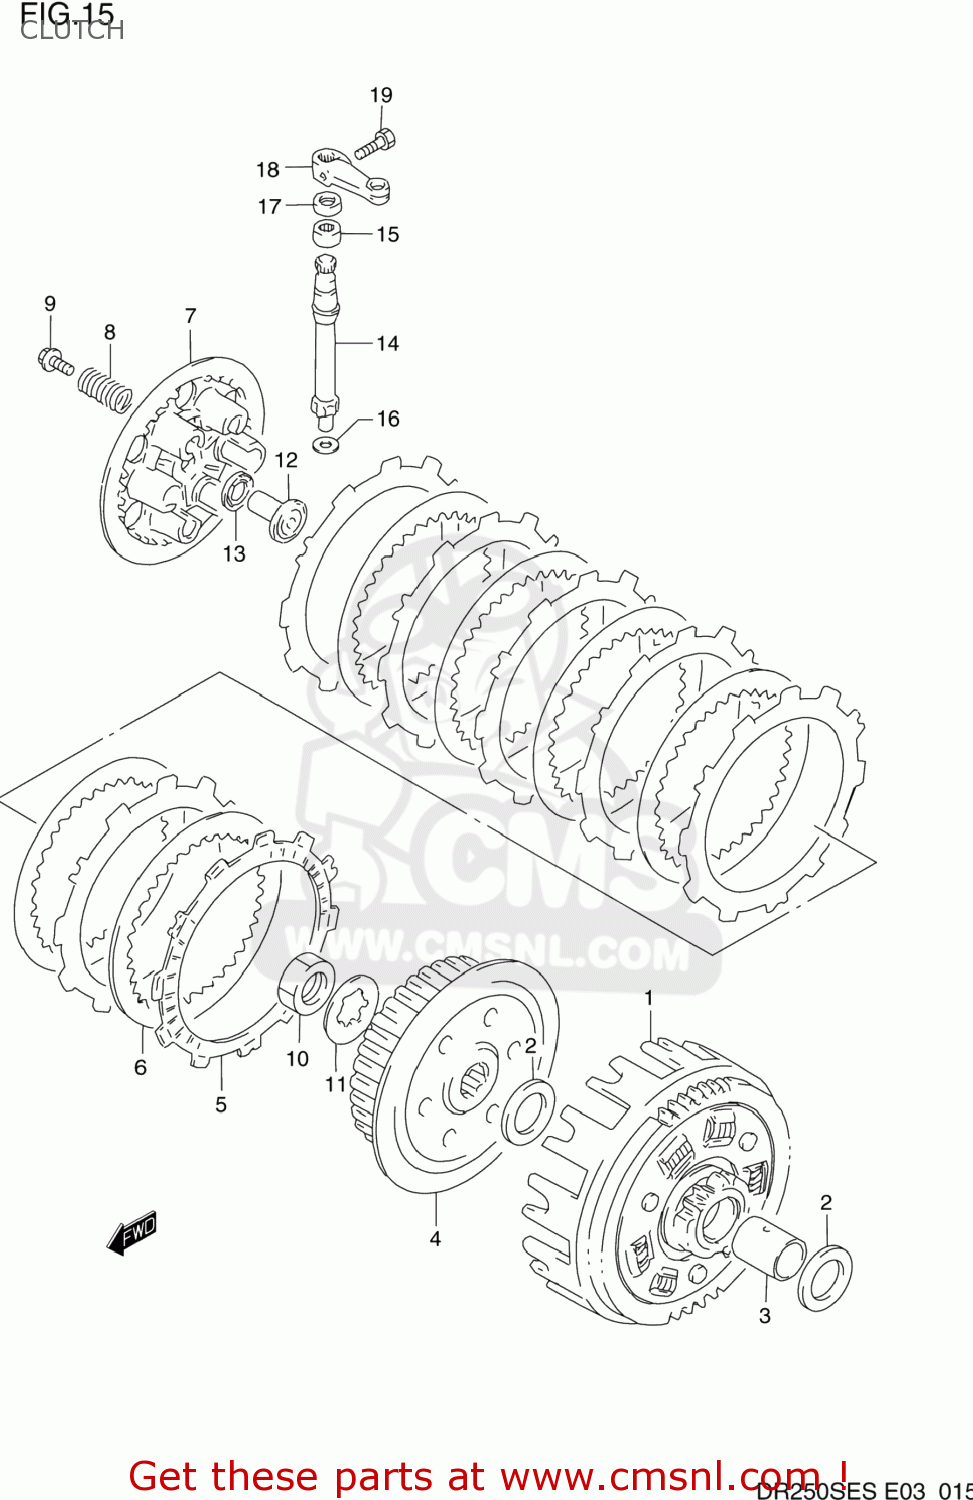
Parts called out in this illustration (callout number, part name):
1	GEAR ASSY,PRI DRIVEN(62/15
2	WASHER
3	SPACER(20X25X29)
4	HUB,CLUTCH SLEEVE
5	PLATE,CLUTCH DRIVE (NAS)
6	PLATE,CLUTCH DRIVEN T: (NAS)
7	DISC,CLUTCH PRESSURE
8	SPRING
9	BOLT 5X16
10	NUT (20MM)
11	WASHER,LOCK
12	RACK,CLUTCH RELEASE
13	BEARING(10X22X2.8)
14	PINION,CLUTCH RELEASE
15	BEARING(12X16X10)
16	WASHER
17	SEAL,OIL(10X17X5)
18	ARM,CLUTCH RELEASE
19	BOLT
